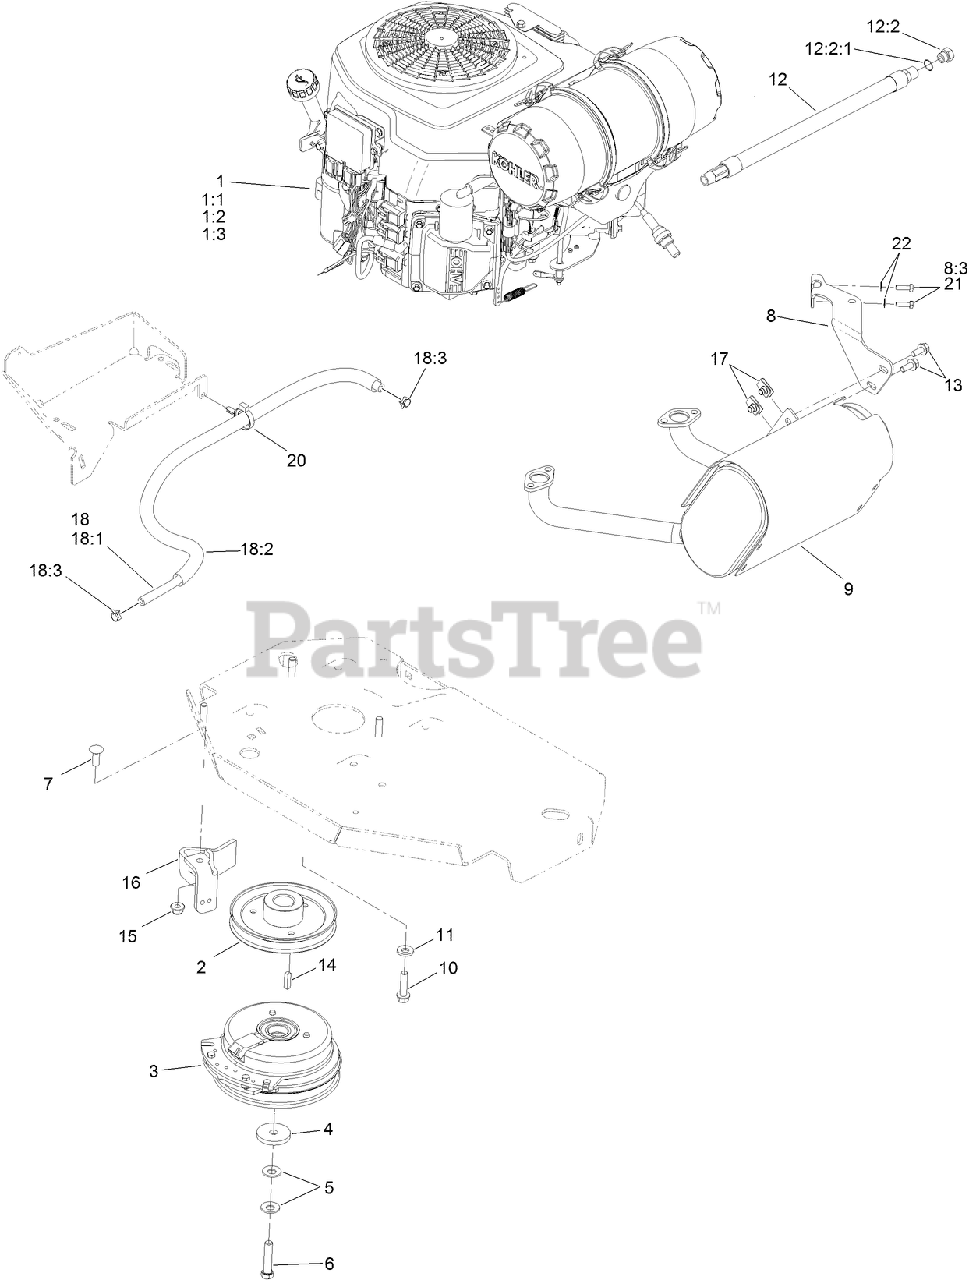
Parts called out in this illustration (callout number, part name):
1:1	KOHLER 52 050 02-S ENGINE OIL FILTER
1:2	KOHLER 25 083 01-S ENGINE AIR FILTER
1:3	KOHLER 25 083 04-S SAFETY FILTER
2	SHEAVE
3	CLUTCH KIT
4	WASHER-CLUTCH
5	WASHER-SPRING
6	SCREW-HH
7	SCREW-CARR
8	BRACKET-MUFFLER
8	MUFFLER BRACKET KIT
8:3	SCREW-HH
9	MUFFLER--KIT
10	SCREW-HWH
11	WASHER-BELLEVILLE
12	OIL DRAIN HOSE ASM
12:2	PLUG-HH
12:2:1	O-RING
13	SCREW-HHF
15	NUT-HF, NI
16	CLUTCH-ANCHOR
17	NUT-U
18	FUEL LINE ASM
18:1	HOSE-FUEL
18:2	SLEEVE-THERMAL
18:3	CLAMP-HOSE
20	CLAMP-HOSE
21	SCREW-HH
22	WASHER-SPRING
